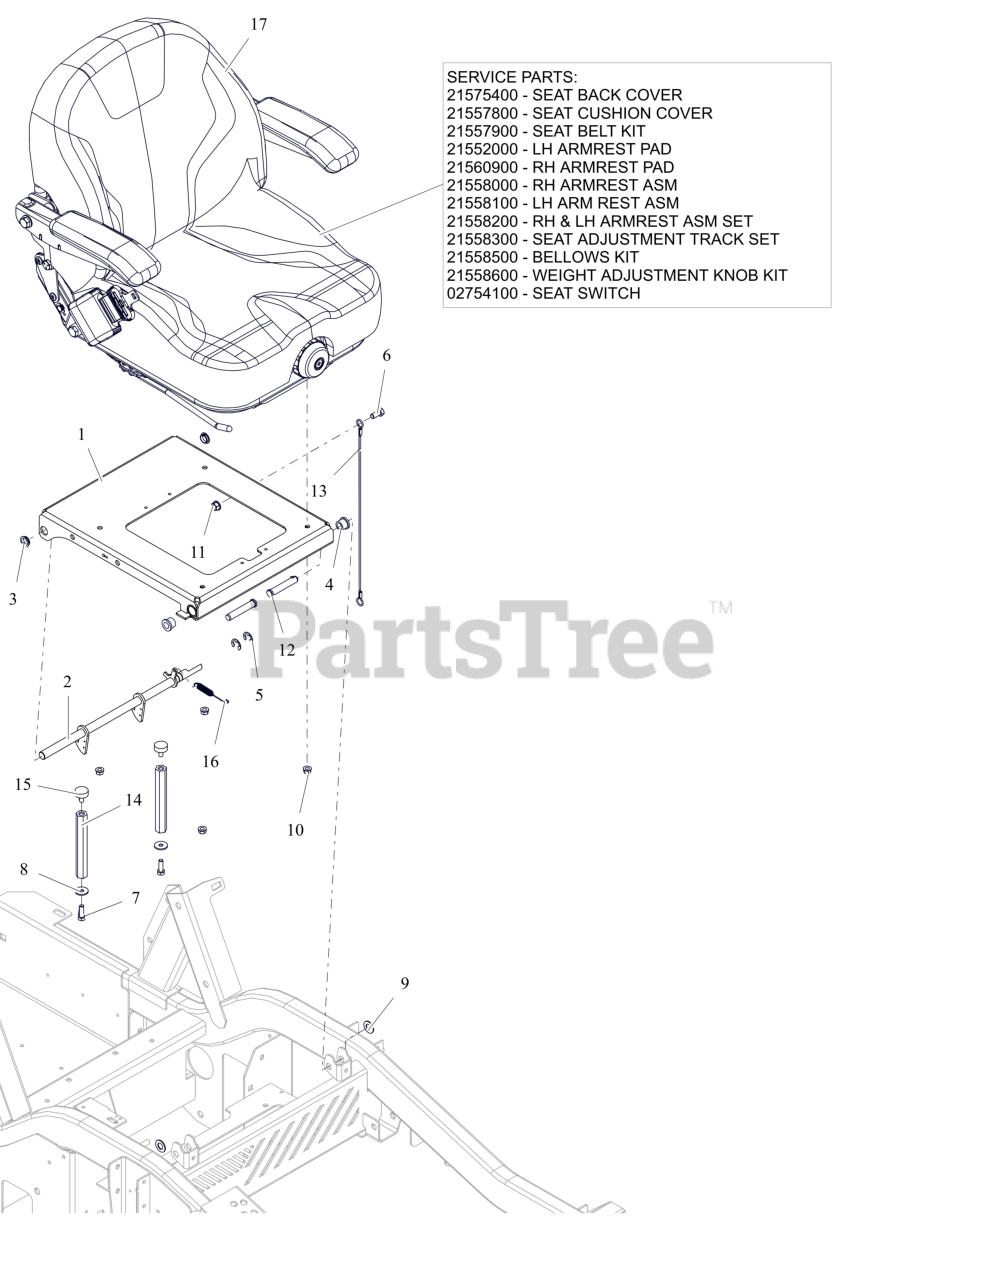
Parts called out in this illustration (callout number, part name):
1	WLDMT, SEAT PLATE (ORANGE)
2	WLDMT, SEAT LATCH (ORANGE)
3	BUSHING, POLYLINER-.63 SNAPIN
4	BSHG, FLG .516X.750X.625X.937
5	RG-RTNG-EXT .625X.042
6	BLT,HEX .38-16X.75 G5 ZCC
7	BLT, HEX .31-18X1.00 G8 ZCC M
8	WSHR,FLT .328X1.00X.094 ZCC
9	WSHR, FLT .531X1.00X.063 ZCC
10	NUT,LK-CTR-FLG .31-18 GF ZCC
11	NUT-LK-CTR-FLG .375-16 GF ZCC
12	PIN-CLIC .50X2.70X2.31 -ZCC
13	CABLE, WIRE (LANYARD)-.093X16.20
14	NUT, COUPLING .312-18 X 5.715
15	BUMPER, RUBBER
16	SG-TENS .043X.44X3.31 WLD 5.8
17	SEAT, ARIENS MECH SUSPENSION LVR
17	SEAT BACK COVER
17	SEAT CUSHION COVER
17	SEAT BELT KIT
17	PAD, ARMREST
17	PAD, ARMREST (HARD)
17	RH ARMREST ASM
17	LH ARMREST ASM
17	RH & LH ARMREST ASM SET
17	SEAT ADJUSTMENT
17	BELLOWS KIT
17	WEIGHT ADJUSTMENT KNOB KIT
17	SWITCH- SNAP MTG N.O.
